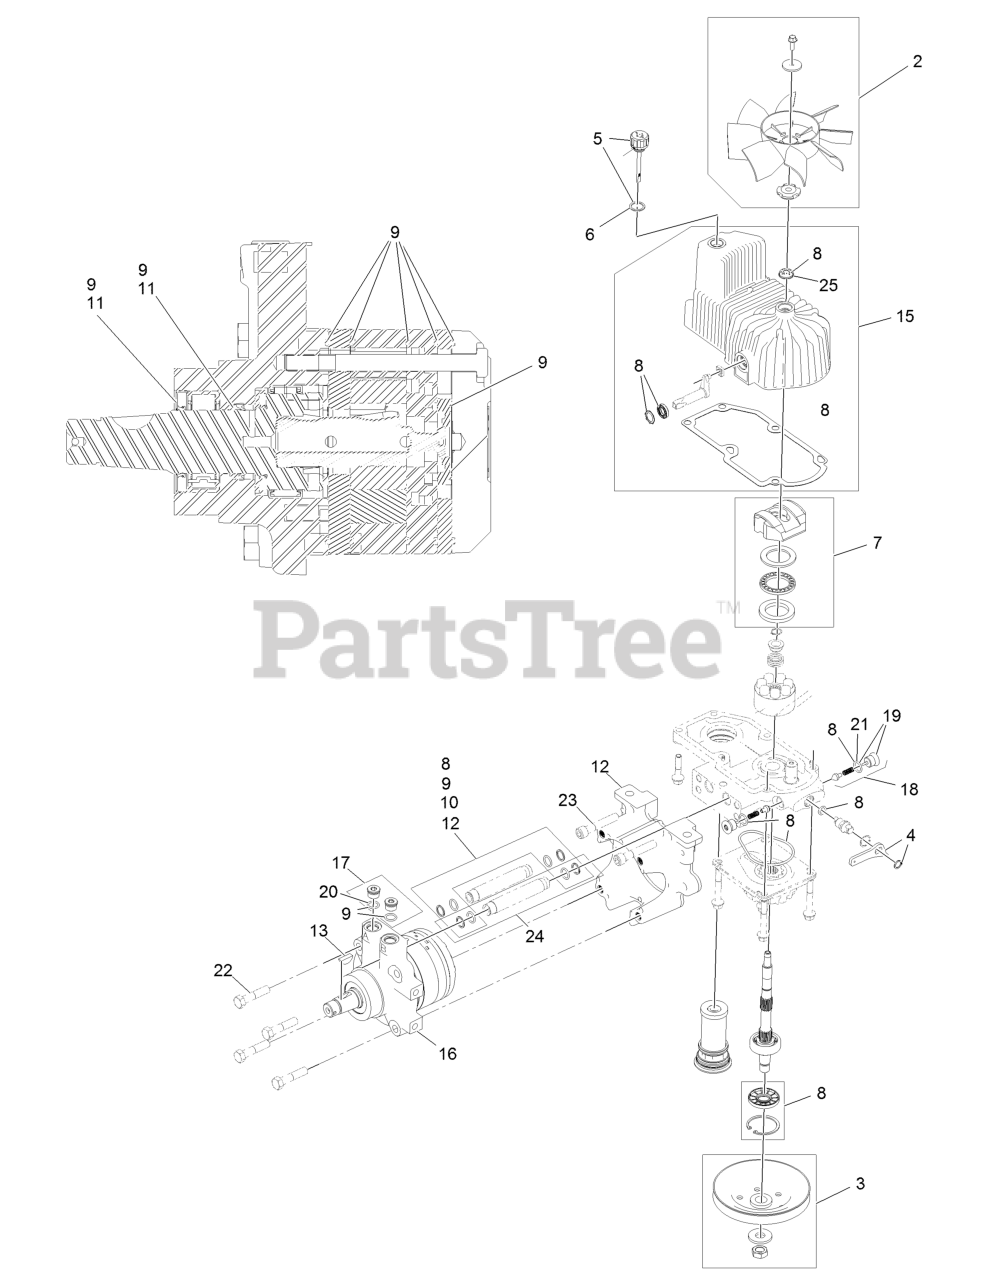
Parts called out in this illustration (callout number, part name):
2	Fan Kit
3	Pulley Kit
4	Handle-Bypass Valve, Hydro
5	Dipstick-Hydro W/Gasket
6	Gasket-Dipstick, Hydro
7	Swash Block Kit
8	Pump Seal Kit
9	Motor Seal Kit
10	Tube Seal Kit
11	Output Shaft Seal Kit
12	Nose Cup-Uht
13	Key-Woodruff 5/16 X 1
15	Housing-LH
16	Motor-Hydraulic LH 240Cc
17	Magnetic Plugs Service Kit
18	Check Valve ASM
19	Plug-Check (W/O-Ring)
21	O-Ring-Check Valve
22	Screw-HH 1/2-20 X 2 1/4
23	Screw-HSH 1/2-20 X 2 3/4
24	Hydraulic Tube Kit
25	Seal-Fan Drive
99	Flow Test Kit
99	Puller-Pulley
